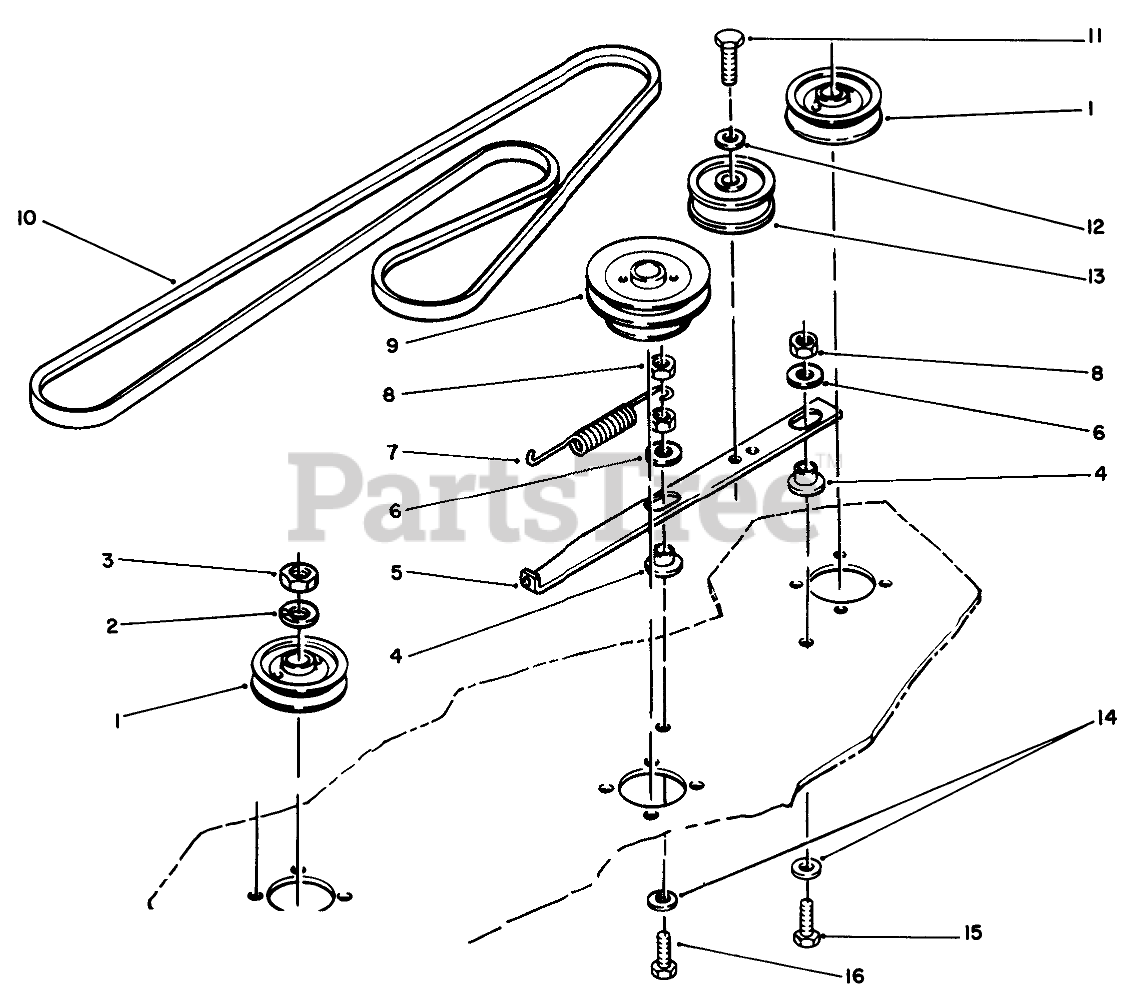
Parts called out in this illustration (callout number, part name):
1	PULLEY
2	Lockwasher
3	Nut
4	SPACER-BUSHING
5	BAR-IDLER SUPPORT
6	WASHER
7	SPRING-EXTENSION
8	NUT
9	PULLEY
10	V-BELT
11	Bolt
12	LOCKWASHER
13	Idler Pulley
14	WASHER
15	Bolt
16	Bolt
